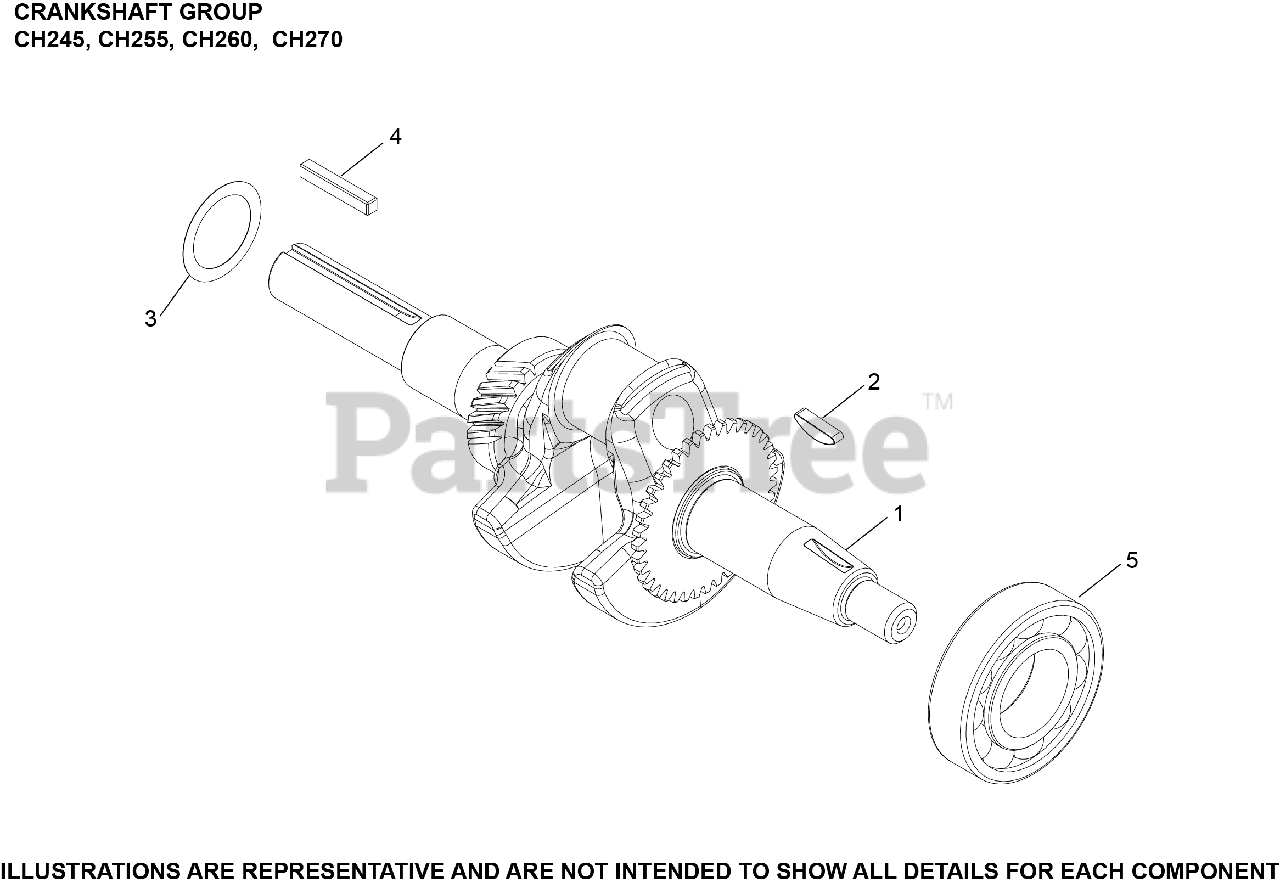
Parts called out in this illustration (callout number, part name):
1	CRANKSHAFT ASSEMBLY
2	KEY, FLYWHEEL
3	KIT, THRUST SHIM
4	KEY, SQUARE
